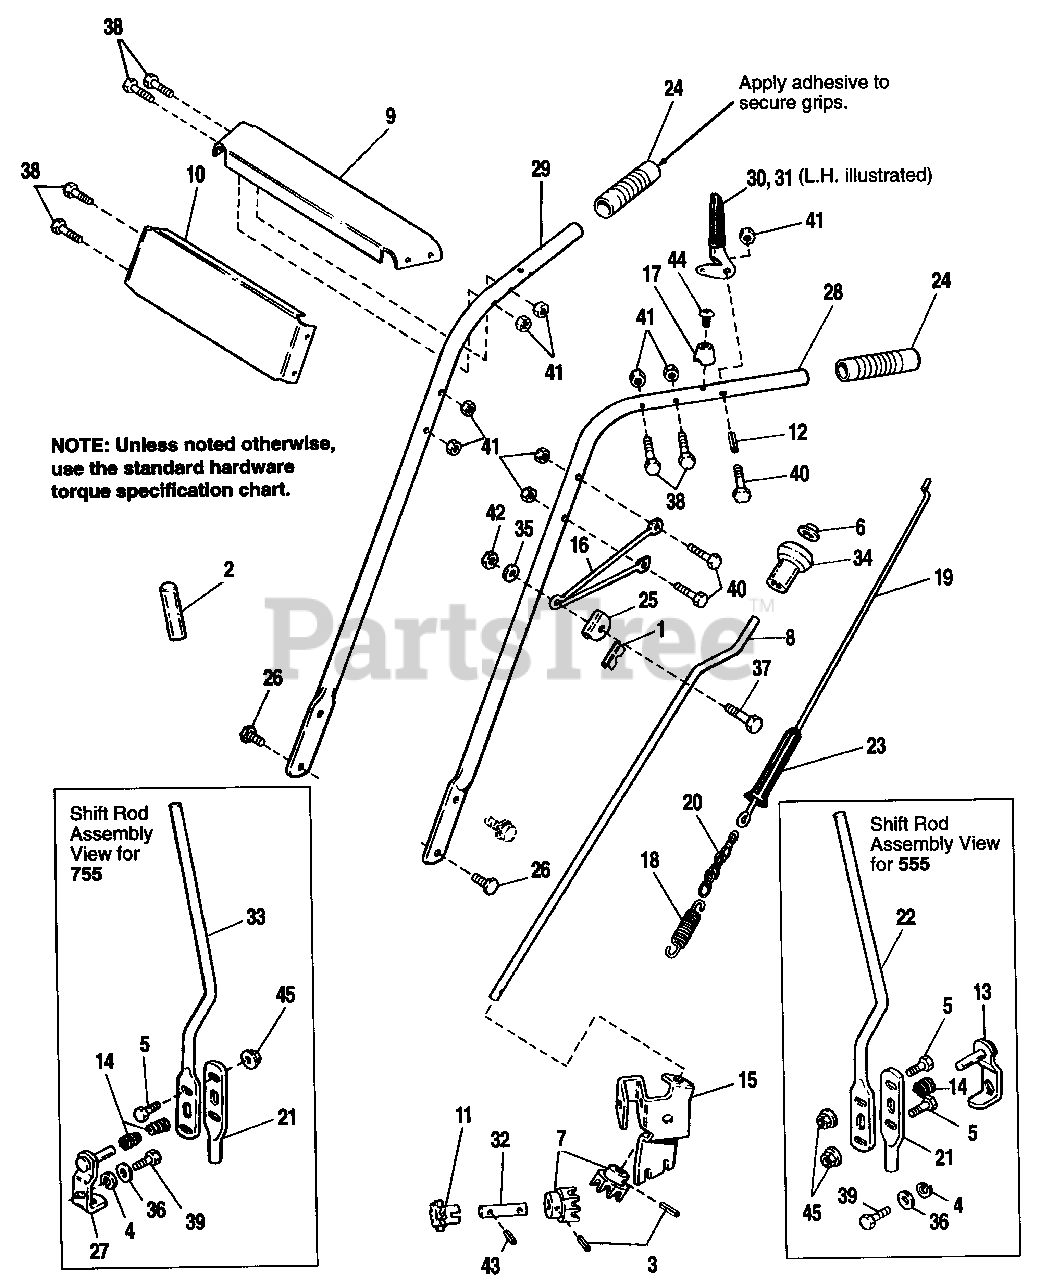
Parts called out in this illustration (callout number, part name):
1	LINER, Rod Guide
3	PIN, Roll, 1/8 x 3/4
4	LOCKWASHER, 1/4
5	CAPSCREW, Hex, 1/4-20 x 3/4
6	PALNUT
7	GEAR, Universal
8	ROD, Chute Control
9	HANDLE PANEL, Upper
10	HANDLE PANEL, Lower
11	SPROCKET, Chute
13	ARM, Shift Assy.-5 HP Only
14	SPRING (Qty. 2 on 7 HP)
15	SUPPORT, Gear
16	BRACKET, Control Rod
19	ROD, Clutch
21	SHIFT ROD, Lower
22	SHIFT ROD, Upper-5 HP Only
23	SLEEVE, Vinyl
24	GRIP, Handle
25	GUIDE, Adj. Rod
26	SCREW, Special, 5/16-18 x 3/4
27	ARM, Shift Assy.-7 HP Only
28	HANDLE, Tube, LH-Black Finish
29	HANDLE, Tube, RH-Black Finish
30	CLUTCH LEVER ASSY., RH
31	CLUTCH LEVER ASSY., LH
32	ROD, Chute, Lower
33	SHIFT ROD, Upper-7 HP Only
34	KNOB, Spinner
35	WASHER, 5/16
36	WASHER, 1/4
37	CAPSCREW, Hex, 5/16-18 x 1-1/2
38	CAPSCREW, Hex, 1/4-20 x 1-1/4
39	CAPSCREW, Hex, 1/4-20 x 5/8
40	CAPSCREW, Hex, 1/4-20 x 1-1/2
41	NUT, Centerlock, 1/4-20
42	NUT, Hex, Centerlock, 5/16-18
43	PIN, Roll, 5/32 x 1
44	SCREW, Thd. Cutting Pan Hd. #10-24
45	NUT, Hex, Whizlock, 1/4-20
